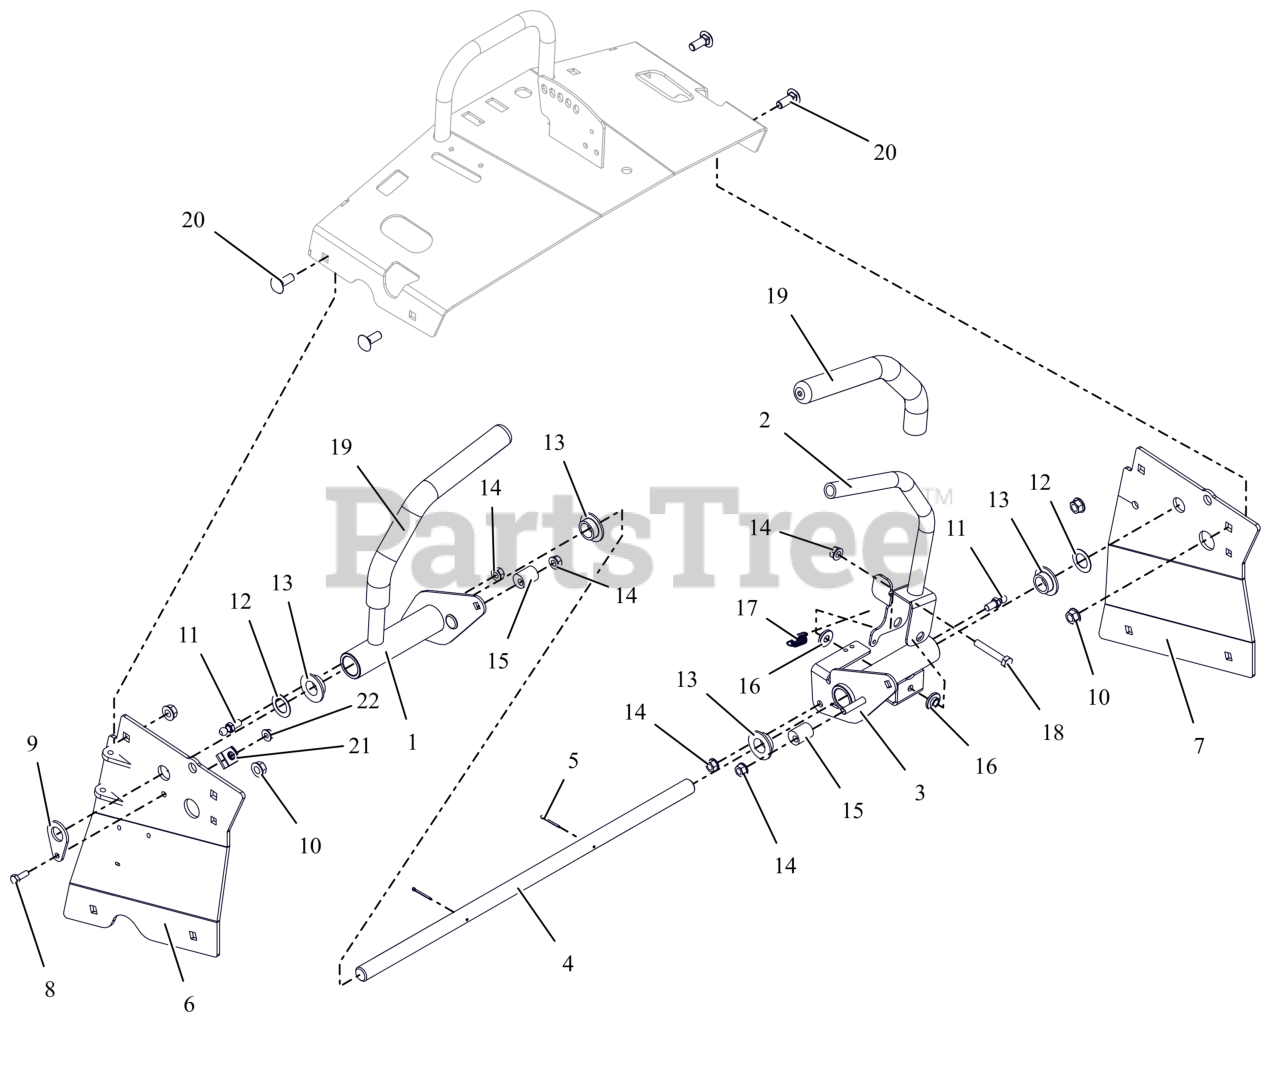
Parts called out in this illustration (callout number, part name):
1	WLDMT-RH STEERING CONTROL(BLK)
2	WLDMT-LH STEERING CONTROL(BLK)
3	WMT-LH STEER CNTRL PIVOT (BLK)
4	SHAFT, CONTROL PIVOT
5	PIN-COTR .09X1.0 PL
6	WMT-48-52"TOWER RH SPPRT(RED)
7	SUPPORT- 48-52" TOWER LH (RED)
8	BLT, HEX .25-20X.75 G5 ZCC
9	PLATE, SHAFT LOCKING
10	NUT-LK-CTR-FLG .375-16 GF ZCC
11	STUD- BALL
12	WSHR-FL-STL 0.76X1.225X0.032 ZCC
13	BSHG-FLG .762X1.48X.44 NYL
14	NUT,LK-CTR-FLG .31-18 GF ZCC
15	ECCENTRIC
16	BSHG, FLG .325X.499X.26X.88
17	SPRING, EXT. .043X.438X1.64
18	BLT, HEX .31-18X2.00 G5 ZCC
19	GRIP, HANDLEBAR
20	BLT, RHSN .38-16X1.00 G5 ZCC
21	CLAMP, CUSHIONED STEEL .75
22	NUT-LK-CTR-FLG .25-20 ZC120
